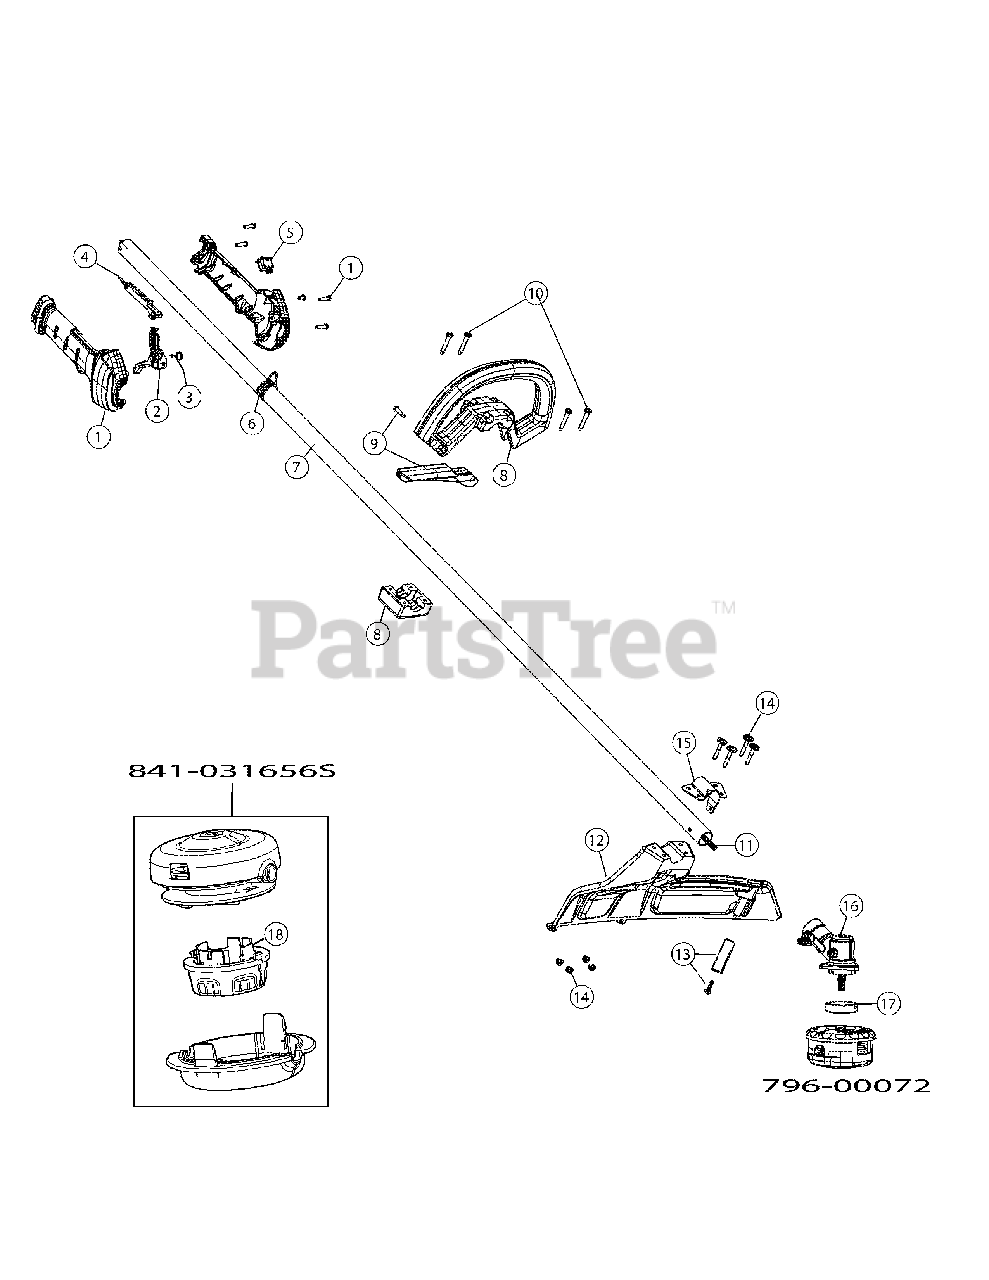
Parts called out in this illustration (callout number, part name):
1	Throttle Housing Assembly
2	Throttle Trigger
4	Throttle Lock-out
6	Shoulder Strap Clip
7	Drive Shaft Housing
8	D-Handle Assembly
9	Barrier Bar Assembly
11	Solid Drive Shaft
12	Shield Assembly
13	Blade Assembly
14	Screw & Nut
15	Guard Mounting Bracket
17	Gearbox Spacer
796-00072	Cutting Head Assembly
841-031656S	Cutting Head Assembly
